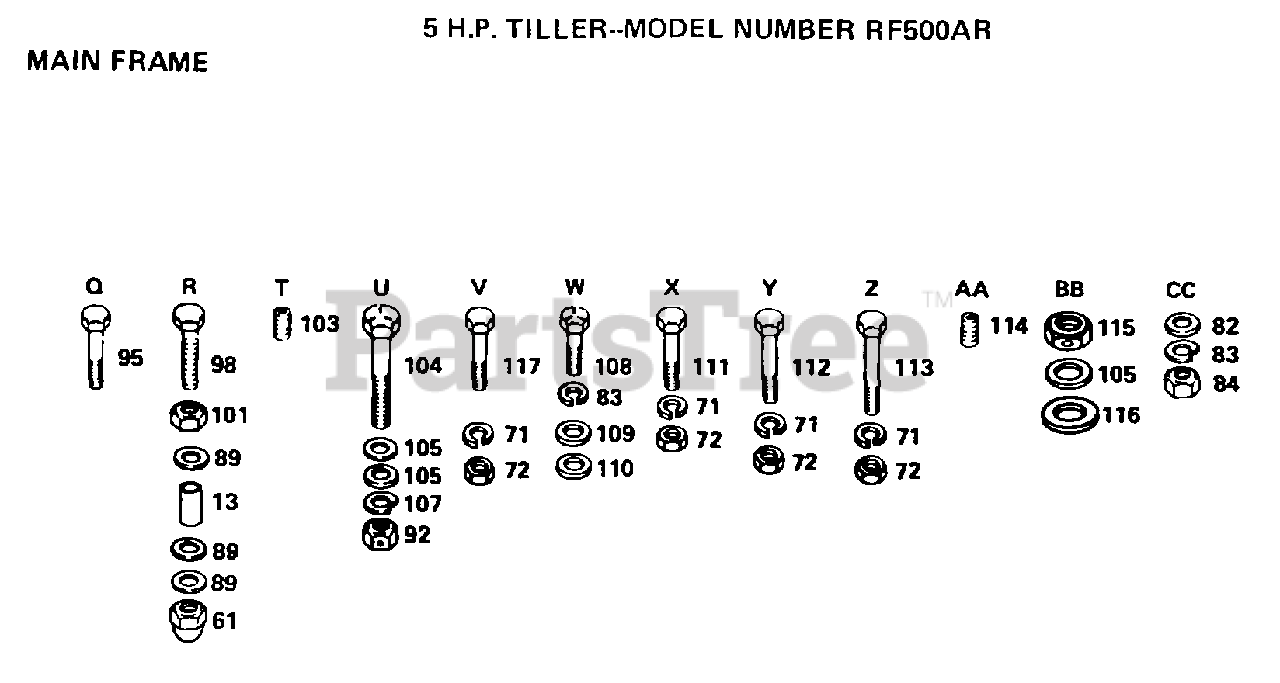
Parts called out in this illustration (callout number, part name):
13	SPACER - SPLIT
71	LOCKWASHER
72	NUT.HEX.5/16-18
82	WASHER
83	LOCKWASHER
89	WASHER
92	GRIPCO NUT
101	NUT.HEX.3/8-16UNC
104	BOLT.3/8-24X3.75
105	WASHER
107	LOCKWASHER
108	BOLT
109	WASHER
110	WASHER
111	BOLT
117	BOLT.HEX.5/16-1.5
